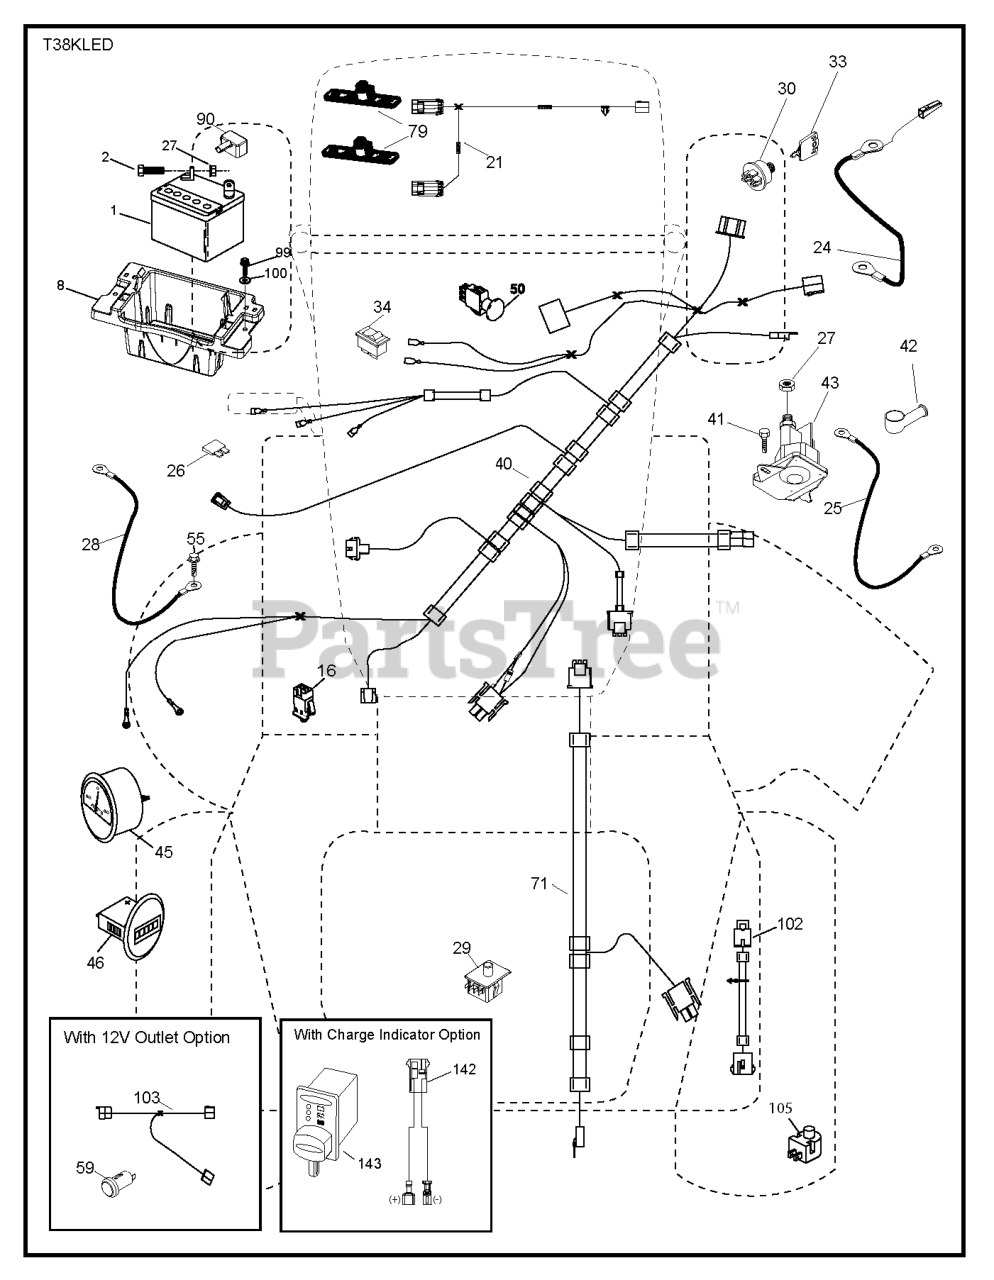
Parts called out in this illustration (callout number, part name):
1	Battery 12 Volt 25 Amp
2	BOLT.HEX.1/4.X.3/4.DICHROMATE
8	TRAY.BATTERY.BOX.FRONT
16	SWITCH INTERLOOK PUSH-IN
24	CABLE.FRBATT.W/WIRE.8GA.8
25	CABLE.STARTER.8GA.17.5
26	FUSE 20AMP
28	CABLE.GROUND.21"BLK.8GA.90T
29	SWITCH.SEAT.DP W/RAMPS
30	SWITCH.IGN.DELTA.W.LGH.ROS
33	KEY.CHAIN.BLISTER.PACK.GEN.USA
40	HARNESS.IGN.DSH.W112V.WPORTWIR
41	SCREW
42	TERMINAL COVER
43	SOLENOID.STARTER.BRASS.PLUNGER
45	GAUGE.AMMETER.SILVER/WHITE
46	GAUGE.HOUR.METER.SILVER/WHITE
50	SWITCH.PTO.8TERMINAL.STD.BLK
55	SCREW 5/16"
59	OUTLET.12-VOLT
71	HARNESS-CHASSIS SUB
90	COVER.TERMINAL.BATTERY
99	SCREW HEXWSHR 1/4-20X3/4
100	WASHER
102	HARNESS PIGTAIL PCH TEX ROS
103	HARNESS.PIGTAIL.12V.OUTLET.
105	REVERSE SWITCH
